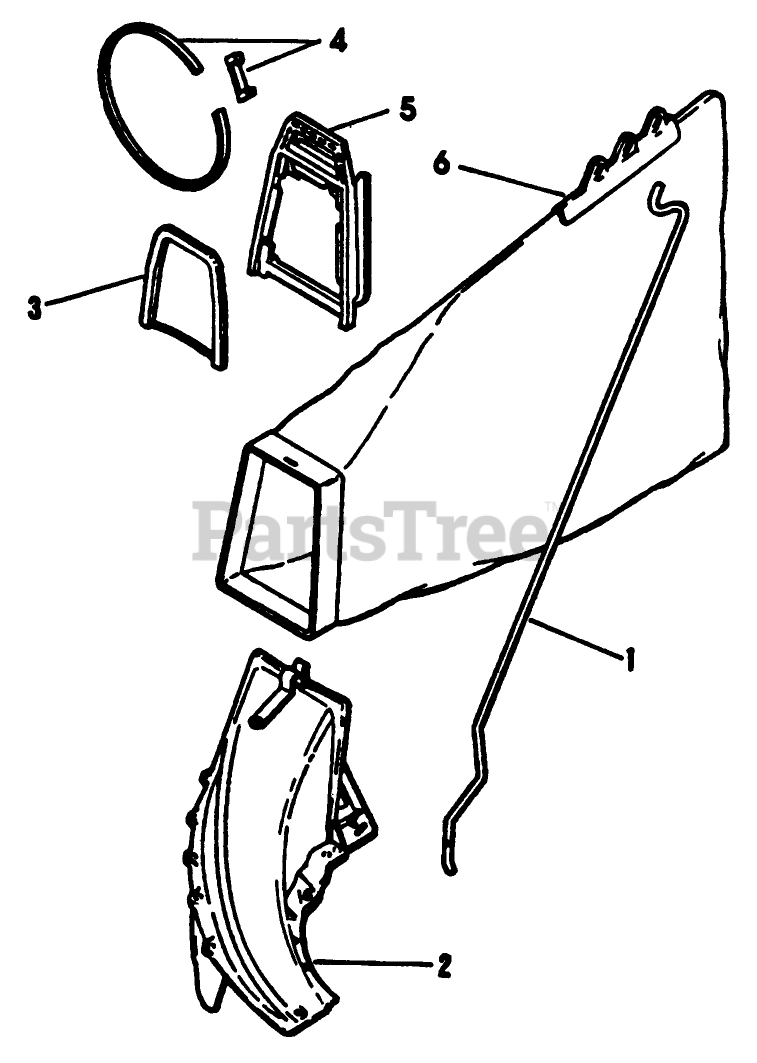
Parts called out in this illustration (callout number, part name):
1	ROD GRASSBAG
3	CHUTE BRACE
5	CHUTE - ADAPTER
6	ORDER 89816 THRU WHOLE GD
